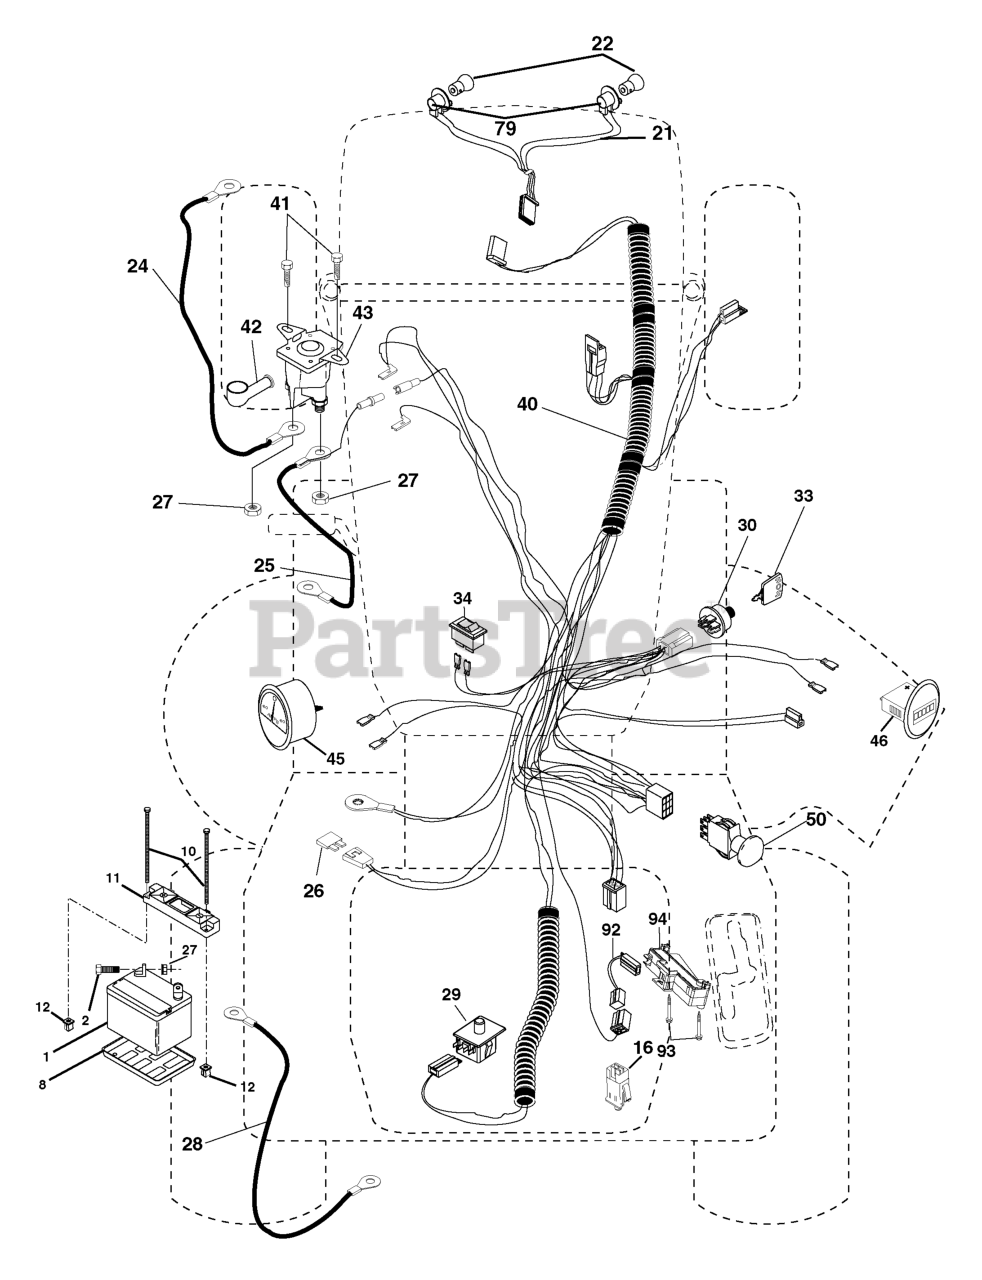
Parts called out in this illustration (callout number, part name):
1	BATTERY 12V .35 AMP
2	BOLT.HEX.1/4.X.3/4.DICHROMATE
8	BATTERY TRAY T
10	BOLT 1/4-20 X 7.5
11	BATTERY HOLDDOWN FRONT MOUNT
12	NUT, PUSH NYLON 1/4" BATTERY
16	SWITCH INTERLOOK PUSH-IN
21	HARNESS.W/LIGHT SOCKET
24	CABLE.STARTER.6GA.22"RED
25	CABLE, BATTERY
27	NUT
28	CABLE, GROUND
29	SWITCH.SEAT.DP W/RAMPS
30	SWITCH.IGN.DELTA.W.LGH.ROS
33	KEY MLD GEN DELTA
40	HARNESS. IGN.VGT.RHD
41	SCREW
42	TERMINAL COVER
43	SOLENOID
45	RP AMMETER.ROUND.SILVER.DELTA
46	RP HOURMETER SNAP-IN
50	RP.PTO.SWITCH.8 TERMINAL.BLACK
79	BULB HOLDER ASM.
92	HARNESS.PIGTAIL.REVERSE.SWITCH
93	SCREW.PLASTITE
94	MODULE.REVERSE.ROS
